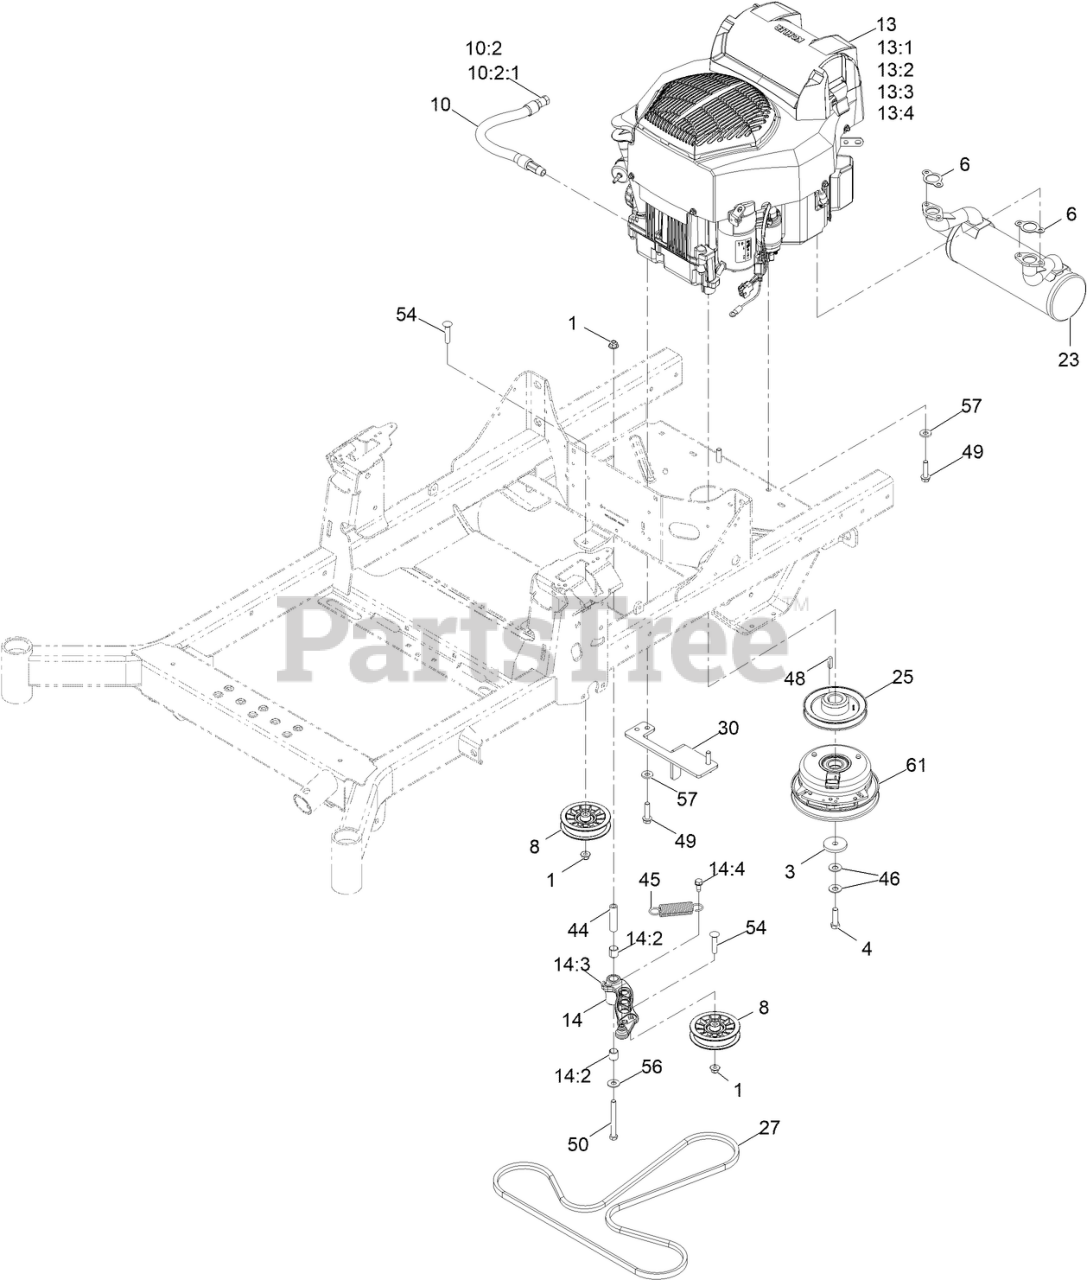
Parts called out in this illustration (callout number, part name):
1	NUT-HF, NI
3	WASHER-CLUTCH
4	SCREW-HH 7/16-20 X 1 1/2 W/LOCTITE
6	GASKET (KOHLER)
8	PULLEY-FLAT IDLER
10	OIL DRAIN HOSE ASM
10:2	PLUG-HH
10:2:1	O-RING
13:1	Kohler 16 083 01-S Engine Air Filter
13:2	Kohler 52 050 02-S Engine Oil Filter
13:3	Kohler 24 050 13-S Fuel Filter
13:4	Kohler 25 083 04-S Safety Filter
14	IDLER ARM ASM
14:2	SLEEVE-BEARING
14:3	FITTING-GREASE, 90 DEG
14:4	SCREW-THD ROLL, HWH
23	MUFFLER-KOHLER AES
25	SHEAVE (W/HUB)
27	BELT-V
30	ANCHOR-CLUTCH
44	BUSHING-PIVOT, IDLER
45	SPRING-EXTENSION
46	WASHER-SPRING
49	SCREW-HWH
50	SCREW-HH
54	SCREW-CARR
56	WASHER-FLAT
57	WASHER-BELLEVILLE
